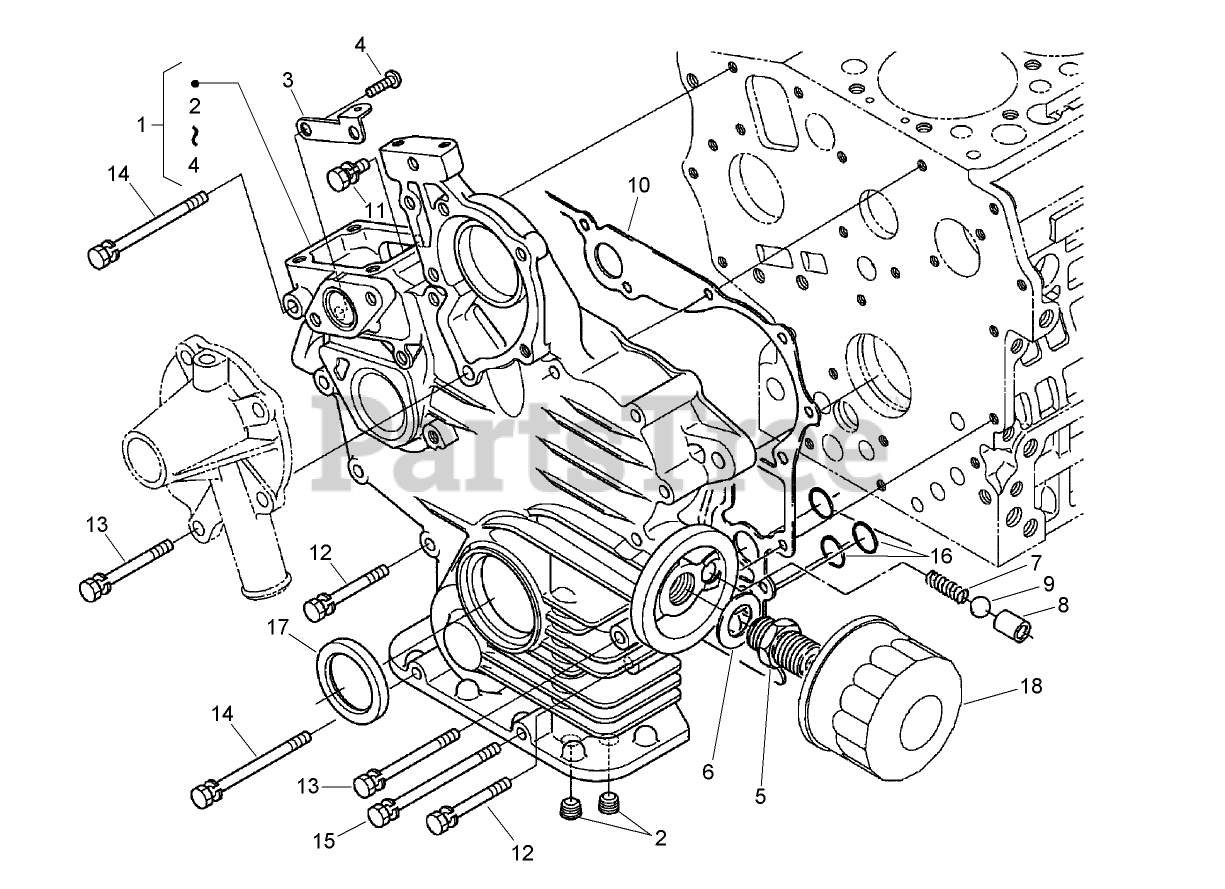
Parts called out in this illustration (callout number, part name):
1	CASE-GEAR
3	STAY-SPRING, START
5	JOINT-PIPE
6	WASHER-PLAIN
7	SPRING
8	SEAT-VALVE
10	GASKET-GEARCASE
12	BOLT
16	O-RING
17	SEAL-OIL
18	CARTRIDGE-FILTER, OIL
